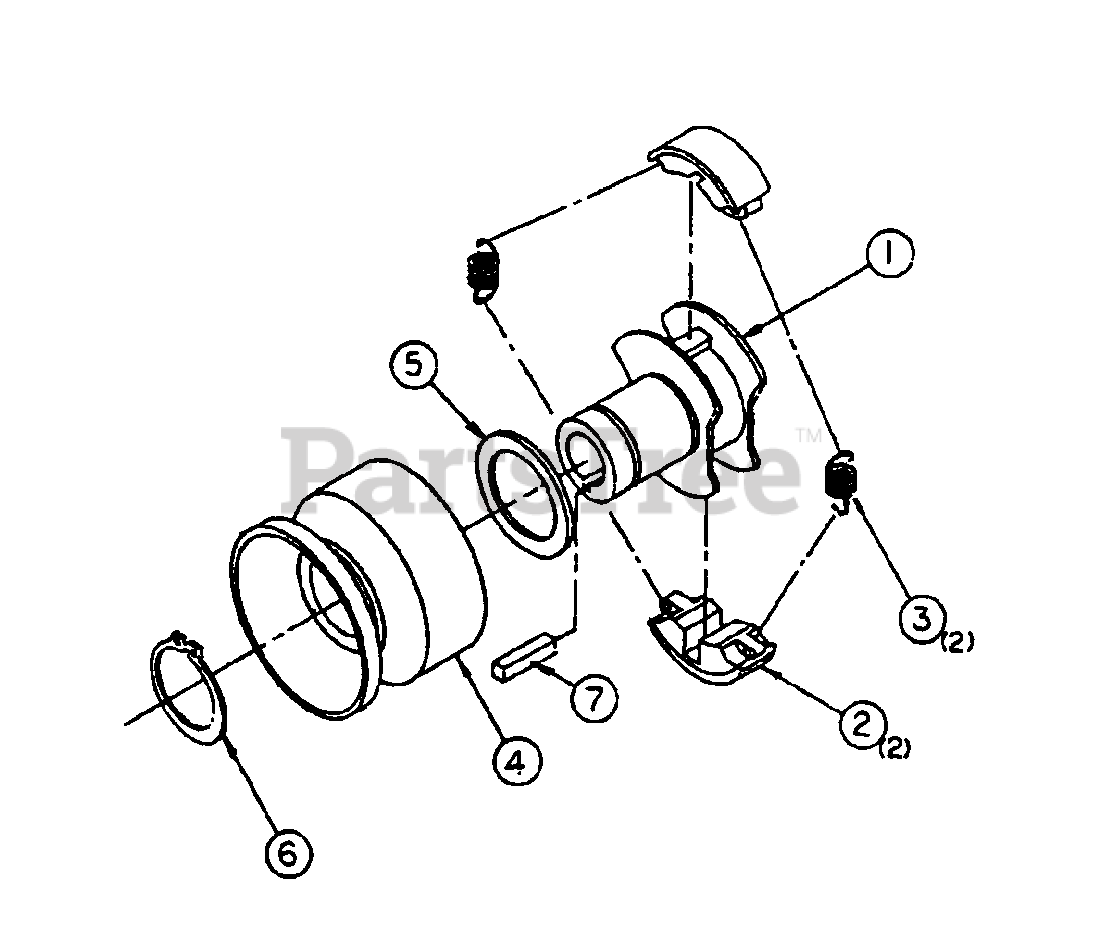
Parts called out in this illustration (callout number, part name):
1	Hub Assembly
3	Spring
4	Drum Assembly
5	Washer
6	Retaining Ring
7	KEY, 3/16x3/16x1"
